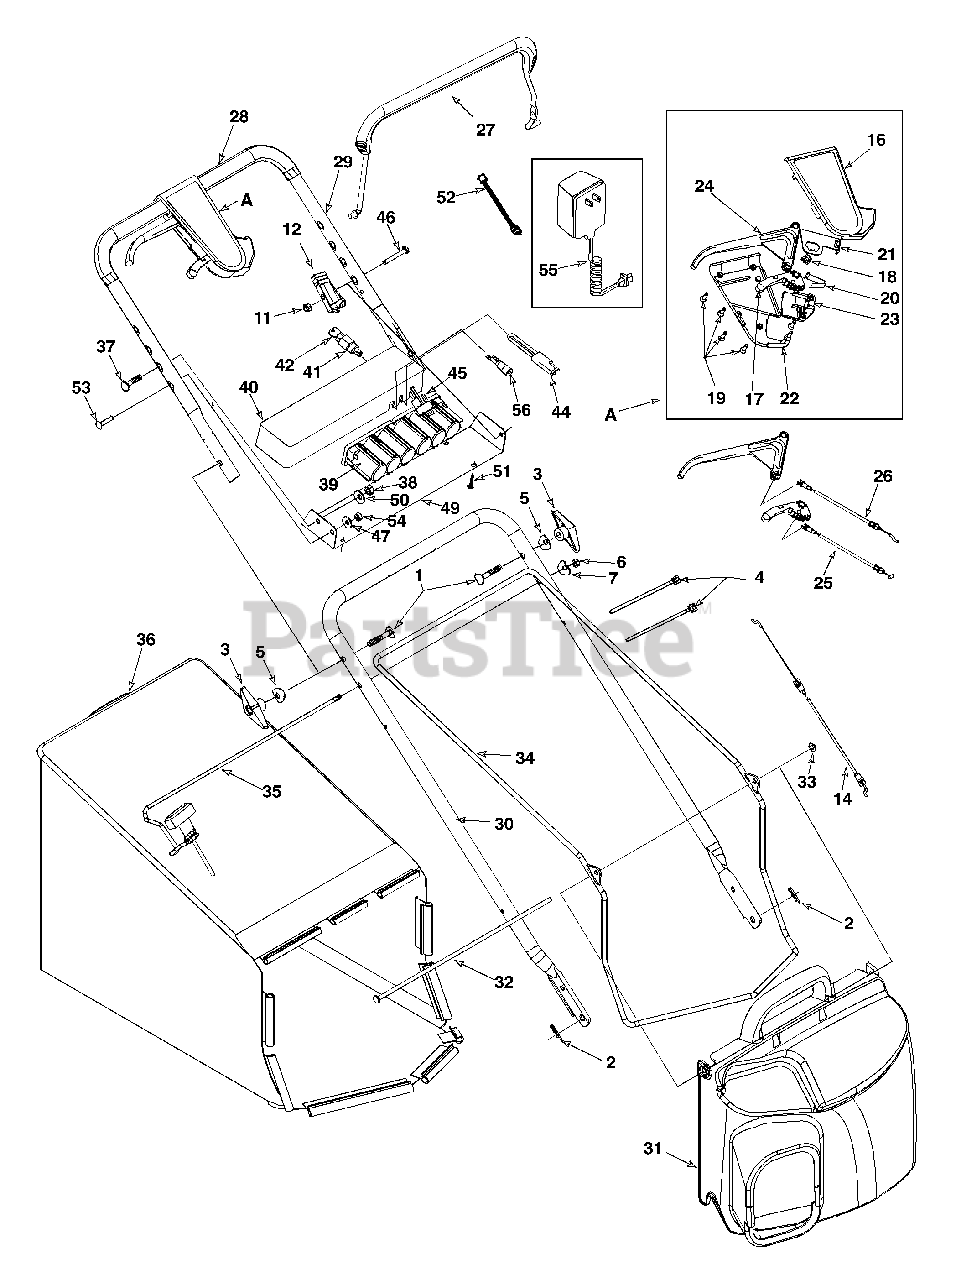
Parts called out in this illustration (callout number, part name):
1	Bolt Cur. Carr. 5/16-18 x 2.0
2	Cotter Pin .072 x 1.12 Lg.
3	Knob Assembly 5/16-18
4	Strap 4.3" Lg.
5	Wash. Sad. .320 ID x.830 OD
6	Handle Knob 1/4-20
7	Saddle Washer
11	Nut 1/4-20 Top Lock Nut Insert
12	Control Cable Housing
14	Control Cable 44" Lg.
16	Upper Control Housing
17	6-Speed Shift Lever
18	Gear Insert
19	C Sunk Tap Screw #10-16x.625
20	Shift Lever Spring
21	6 Spd. Rack Cable Brkt.
22	Lower Control Housing
23	Cable Mounting Cap
24	Control Lever
25	6 Spd. Cable
26	Self Prop. Cable, 52"
27	Control Handle
28	Foam Grip
31	Grass Bag Cover
37	Cur. Carr. Bolt 5/16-18 x 1"
38	Hex Nut 5/16-18 Thd.
39	Battery Pack - 12 Volt
41	Ignition Switch
42	Ignition Key
44	Plug
45	Wire Harness
46	Hex Bolt 1/4-20 x 1.3" Lg.
47	Bell Wash 1/4" I.D.
51	Truss Mch. Tap Scr. 1"
52	Harness Ext.
53	Scr. 1/4-20 x 1.25
54	Hex Nut 1/4-20
55	Battery Charger
56	Fuse Holder
